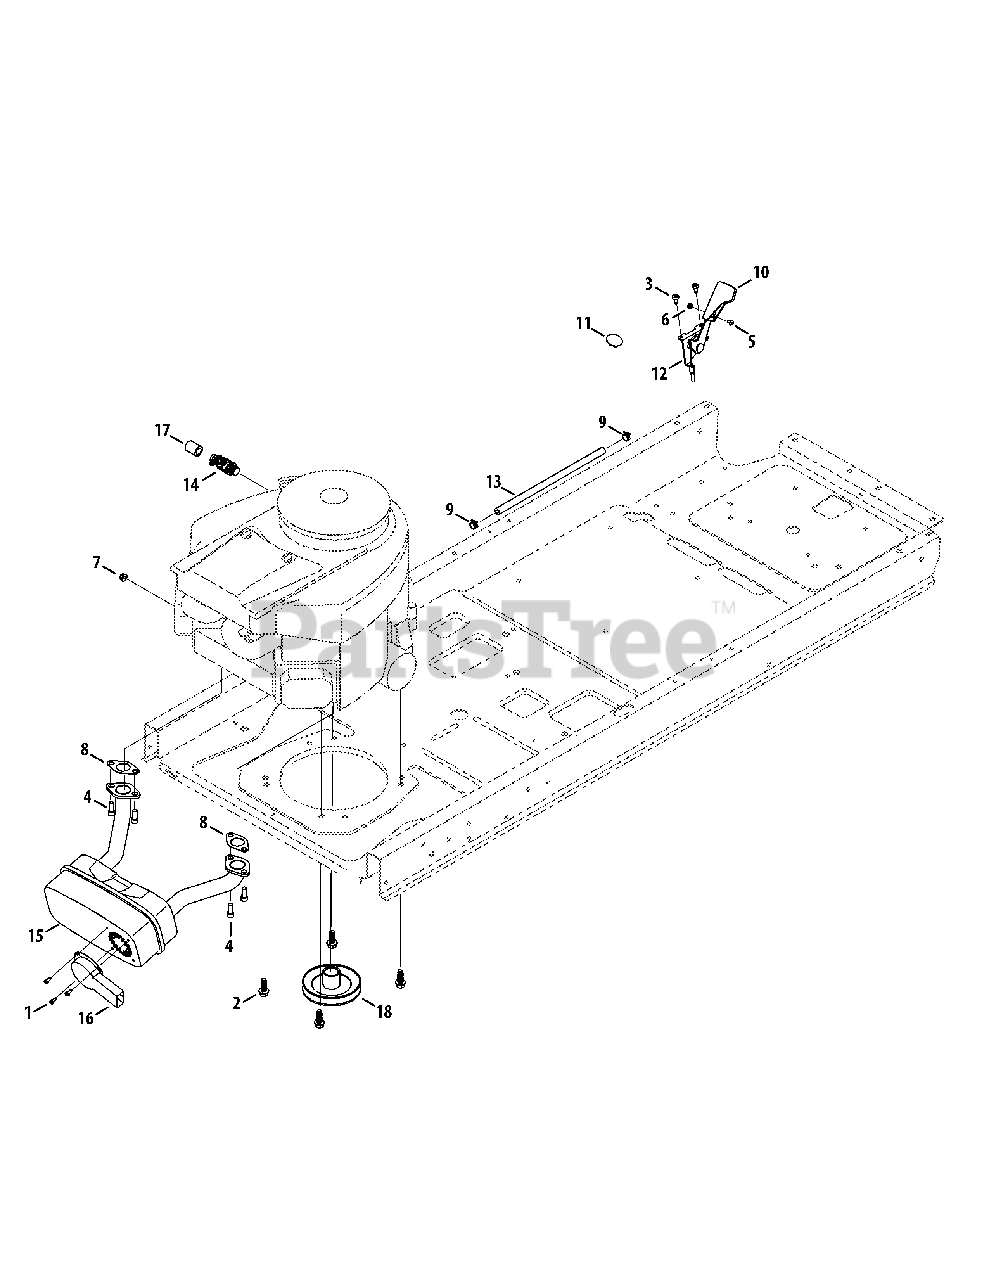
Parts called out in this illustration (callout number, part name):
1	Hex Washer Screw, #8-18 x .500
2	Hex Washer Screw, 3/8-16 x 1.00
3	Screw, 1/4-20 x .50
4	Socket Head Screw, 5/16-18 x .750
5	Screw, #8-32 x .375
6	Hex Nut, #8-32
7	Flange Lock Nut, 1/4-20
8	Exhaust Gasket
9	Hose Clamp, .490 Dia.
10	Throttle Control Knob
11	Choke Plug
12	Throttle/Choke Control Cable
13	Fuel Hose, 1/4
14	Oil Drain
15	Muffler, Intek Twin
16	Muffler Deflector Long
17	Oil Drain Hose
18	Engine Pulley
